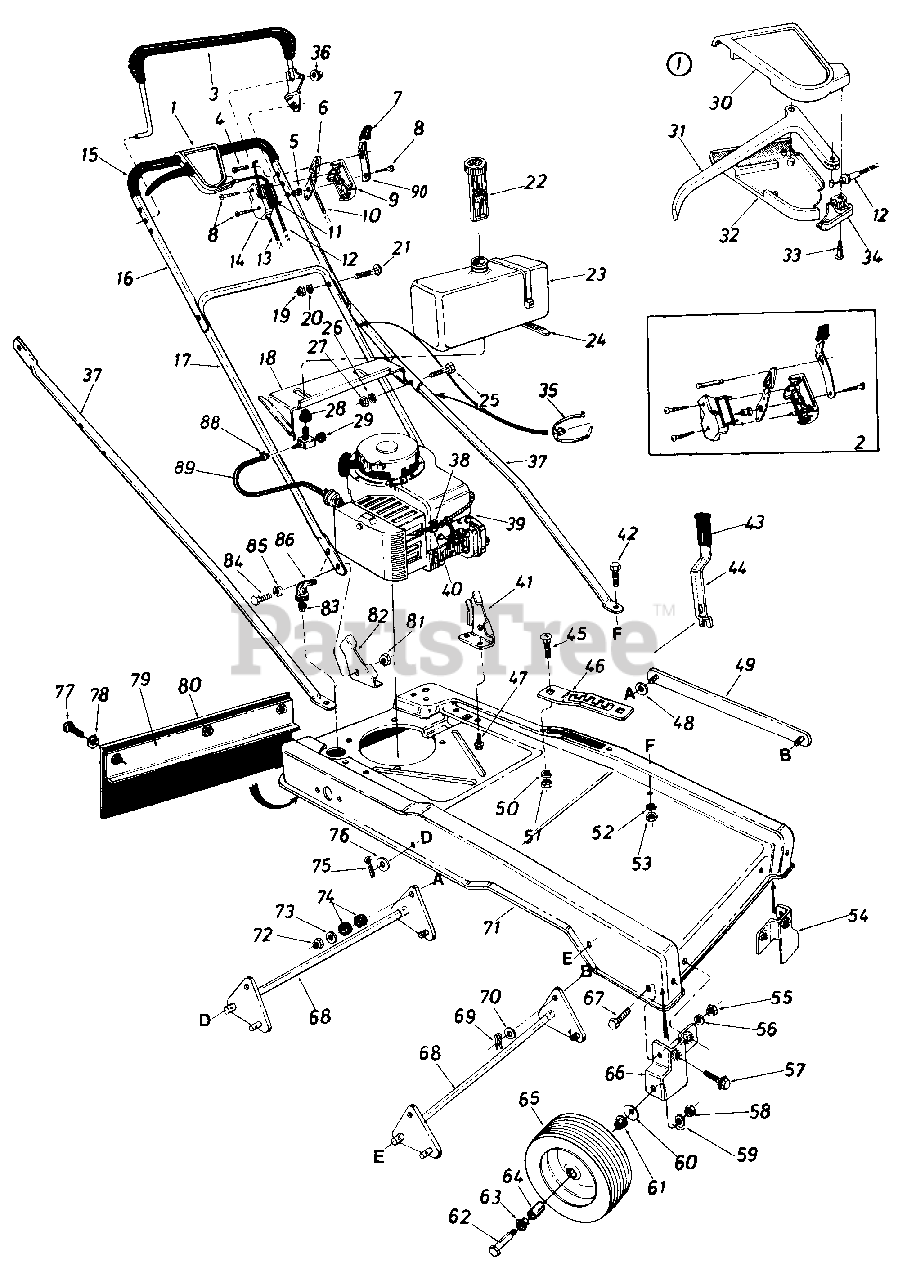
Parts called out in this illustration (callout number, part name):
1	Clutch Control Housing Comp.
2	Control Housing Comp.
3	Control Handle Ass'y.
4	Lock Pin
5	Control Disc Pin
6	Throttle Control Lever
7	Spring Lever Knob
8	Truss Mach. Hi-B Tap Scr. #12 x 1.50" Lg.
9	Control Panel Half
10	Throttle Control Wire 43" Lg.
11	Control Label Throttle
12	Self-Propelled Cable 50" Lg.
13	Drive Clutch Cable 46" Lg.
14	Clutch Panel Half
15	Grip 22" Lg.
16	Upper Handle (Painted)
17	Lower Handle (Painted)
18	Gas Tank Mounting Brkt.
19	Hex Nut 5/16-18 Thd.
20	L-Wash. 5/16" I.D.
21	Carriage Bolt 5/16-18 x 1.50" Lg.
22	Gas Gauge 13/4-6 x 5.50" Lg.
23	Gas Tank
24	Cable Tie 30.6" Lg.
25	Hex Bolt 5/16-24 x 1.25" Lg.
26	L-Wash. 5/16" I.D.
27	Hex Nut 5/16-24 Thd.
28	Bushing Gas Tank
29	Fuel Shut-Off Valve w/Screen
30	Control Cover Half Upper
31	Control Lever
32	Control Cover Half Lower
33	Flat "C" Sunk Hd. Tap Scr. #10 x .75" Lg.
34	Cable Mounting Cap
35	Cable Tie
36	Push Cap
37	Strut .75" O.D. x 43.44" Lg.
38	Hex Sems Scr. #10-32 x .62" Lg.
39	Engine 5 H.P.
40	Casing Clamp
41	Handle Mount Brkt. L.H.
42	Hex Bolt 5/16-18 x .75" Lg.
43	Grip Black
44	Lift Handle
45	Carriage Bolt 5/16-18 x .62" Lg.
46	Lift Handle Support Brkt.
47	Hex Wash. Hd. B-Tap Scr. 5/16-18 x .50
48	Fl-Wash. .406" I.D. x 1.25" O.D.
49	Connecting Link Ass'y.
50	L-Wash. 5/16" I.D.
51	Hex Nut 5/16-18 Thd.
52	L-Wash. 5/16" I.D.
53	Hex Nut 5/16-18 Thd.
54	Wheel Brkt. Ass'y. L.H.
55	Hex Nut 5/16-18 Thd.
56	L-Wash. 5/16" I.D.
57	Hex Sems Bolt 5/16-18 x .75" Lg.
58	Hex Cent. L-Nut 3/8-16 Thd.
59	L-Wash. 3/8" I.D.
60	Bell-Wash. .400" I.D. x .88" O.D.
61	Flanged Ball Brg. 3/8" I.D.
62	Hex Bolt 3/8-16 x 2.00" Lg.
63	Flanged Ball Brg. .501" I.D.
64	Spacer .375" I.D. x .505" O.D. x 1" Lg.
66	Wheel Brkt. Ass'y. R.H.
67	Hex Sems Bolt 5/16-18 x .75" Lg.
68	Lift Brkt. Shaft Ass'y.
69	Intern. Cotter Pin 5/16" Dia.
70	Fl-Wash. .385" I.D. x .88"
71	Hi-Wheel Frame
72	Hex Ins. L-Nut 3/8-24 Thd.
73	Fl-Wash. .385" I.D. x .88"
74	Rubber Wash. .33" I.D. x .87" O.D.
75	Cotter Pin 1/8" Dia. x 1" Lg.
76	Fl-Wash. .51" I.D. x 1.0"
77	Hex Bolt 1/4-20 x .62" Lg.
78	L-Wash. 1/4" I.D.
79	Retaining Strip Ass'y. 3" x 15" Lg.
80	Rear Flap 7.5 x 20" Lg.
81	Hex Nut 3/8-16 Thd.
82	Handle Mount Brkt. R.H.
83	Part of Engine
84	Hex Bolt 3/8-16 x .75" Lg.
85	L-Wash. 3/8" I.D.
86	90 Deg. Elbow Male to Female 3/8
88	Hose Clamp .406" Dia.
89	Fuel Line 15" Lg.
90	Lockout Lever
